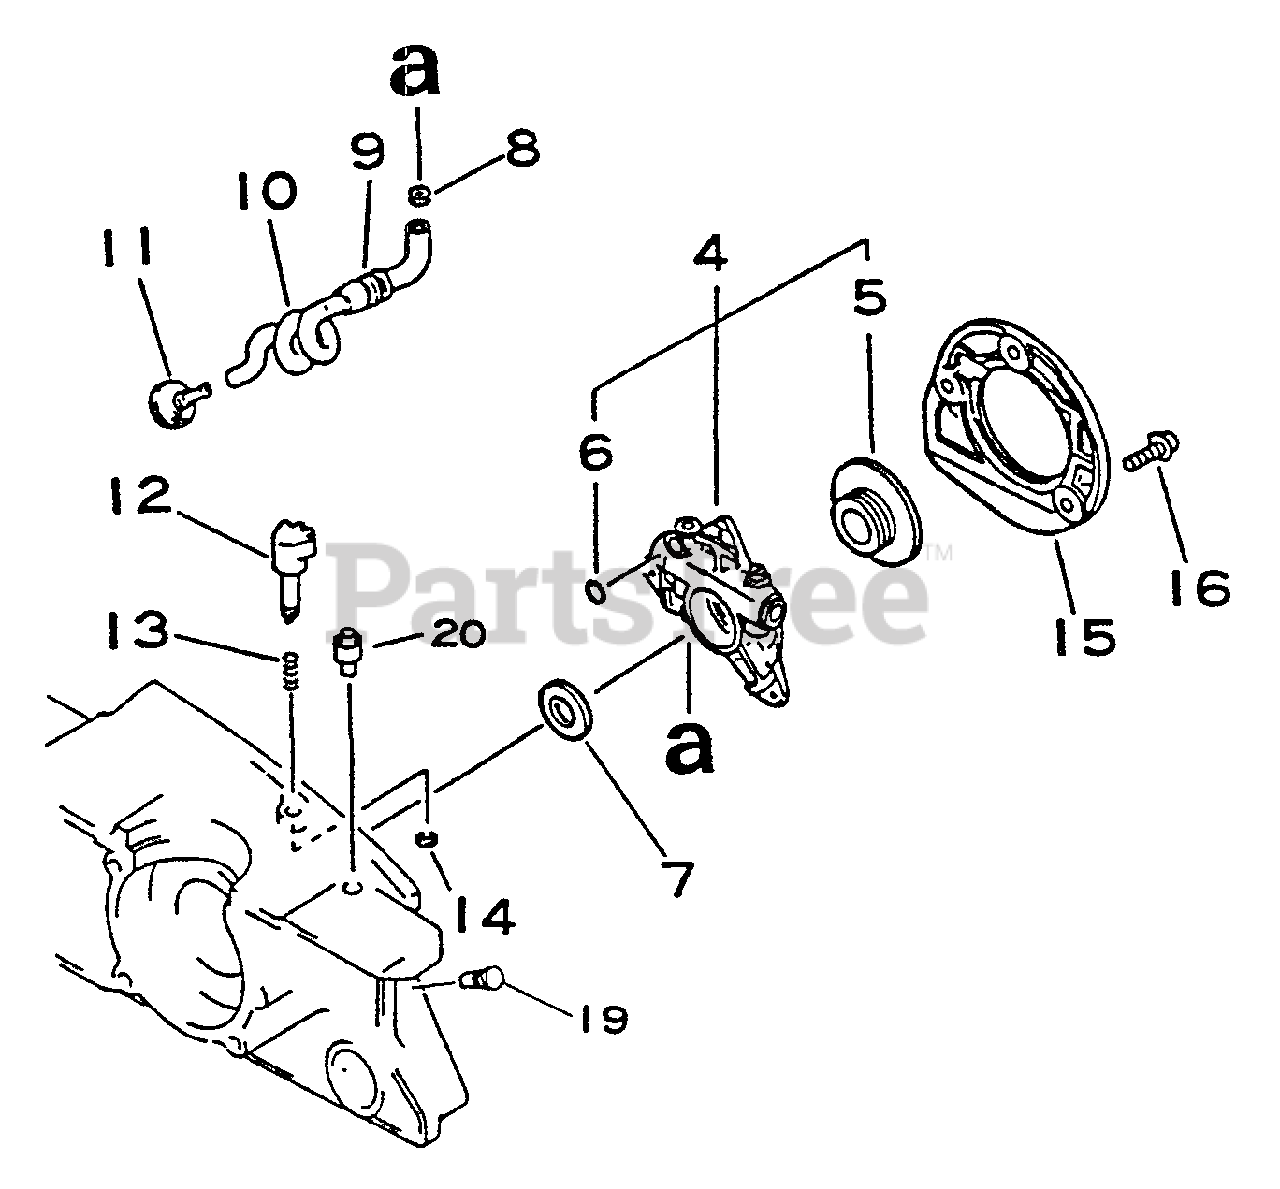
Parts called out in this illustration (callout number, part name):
4	AUTO-OILER ASSY
5	WHEEL, WORM
6	O-RING - 3
8	CLIP - 6.5
10	PIPE, OIL - SPIRAL
11	FILTER, OIL
12	DIAL, AUTO-OILER
14	RING, RETAINING - 3
15	COVER, OIL PUMP
16	SCREW - 4X14
19	PLUG
20	PLUG
